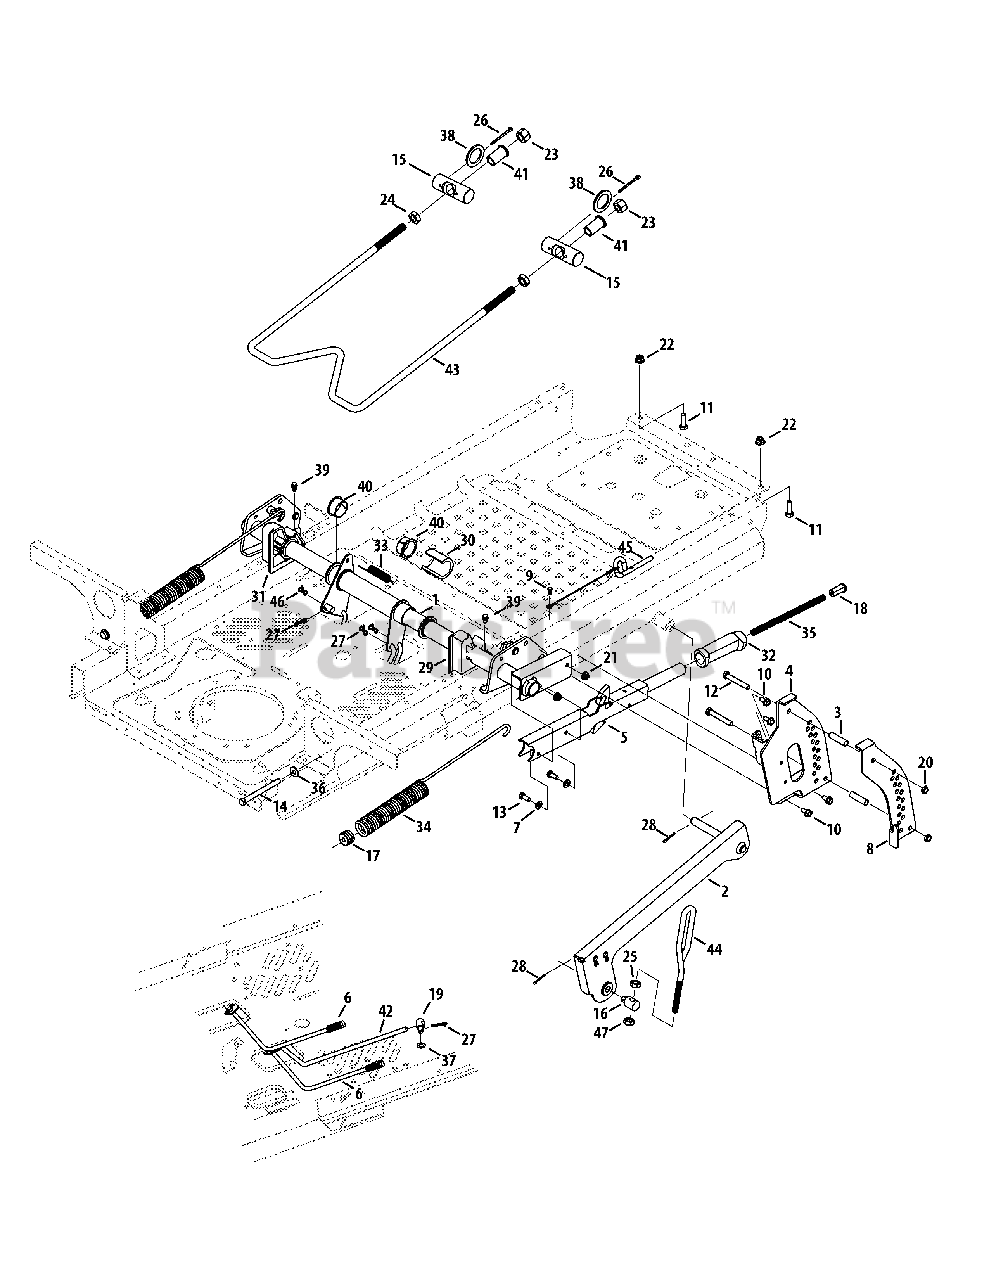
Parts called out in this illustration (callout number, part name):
1	Deck Lift Shift Assembly
3	Spacer, .386 x .63 x 1.75
4	Index Bracket Assembly
5	Latch Handle Assembly
6	Brake Rod Assembly
7	Flat Washer .330 ID x .630 OD
8	Outer Index Bracket
9	Screw, #10-16, .50
10	Hex Washer Screw, 5/16-18 x .750
11	Hex Screw, 3/8-16 x 1.00
12	Hex Head Screw, 3/8-16 x 2.50
13	Hex Cap Screw, 5/16-18 x .75
14	Hex Screw, 3/8-16 x 4.25
15	Pivot Pin, 1.25
16	Ferrule, .496 x .528
17	Spring Insert
18	Handle Button
19	Ferrule, 3/8-24 x .375
20	Jam Lock Nut, 3/8-16
21	Flange Lock Nut, 5/16-18
22	Flange Lock Nut, 3/8-16
23	Nylock Nut, 5/8-11
24	Jam Nut, 5/8-11
25	Nut, Jam, 1/2-13
26	Cotter Pin, 3/16 x 2.0
27	Bow-Tie Cotter Pin
28	Cotter Pin 1/8 x 1.25
29	Deck Lift Bracket
30	Spacer, 1.375 Shaft
31	Deck Lift Bracket, LH
32	Grip, Deck Lift Handle
33	Extension Spring, .63 Dia. x 4.95 LG
34	Extension Spring, 1.485 OD x 17.58
35	Spring, Compression, .4 x 8.52
36	Flat Washer, .385 x .870 x .092
37	Washer, .375 x .700 x .030
38	Flat Washer, 1.875 x 1.38 x .097
39	Shoulder Screw, .500 x 1/4-20
40	Flange Bearing, 1.38 x 1.75 x .50
41	Flange Bearing, .875 x .702 x 1.10
43	Deck Hanger Rod, 5/8
44	Lift Adjust Link
45	Lock Rod, .375
46	Bow-Tie Cotter Pin
47	Hex Nut, 1/2-13
